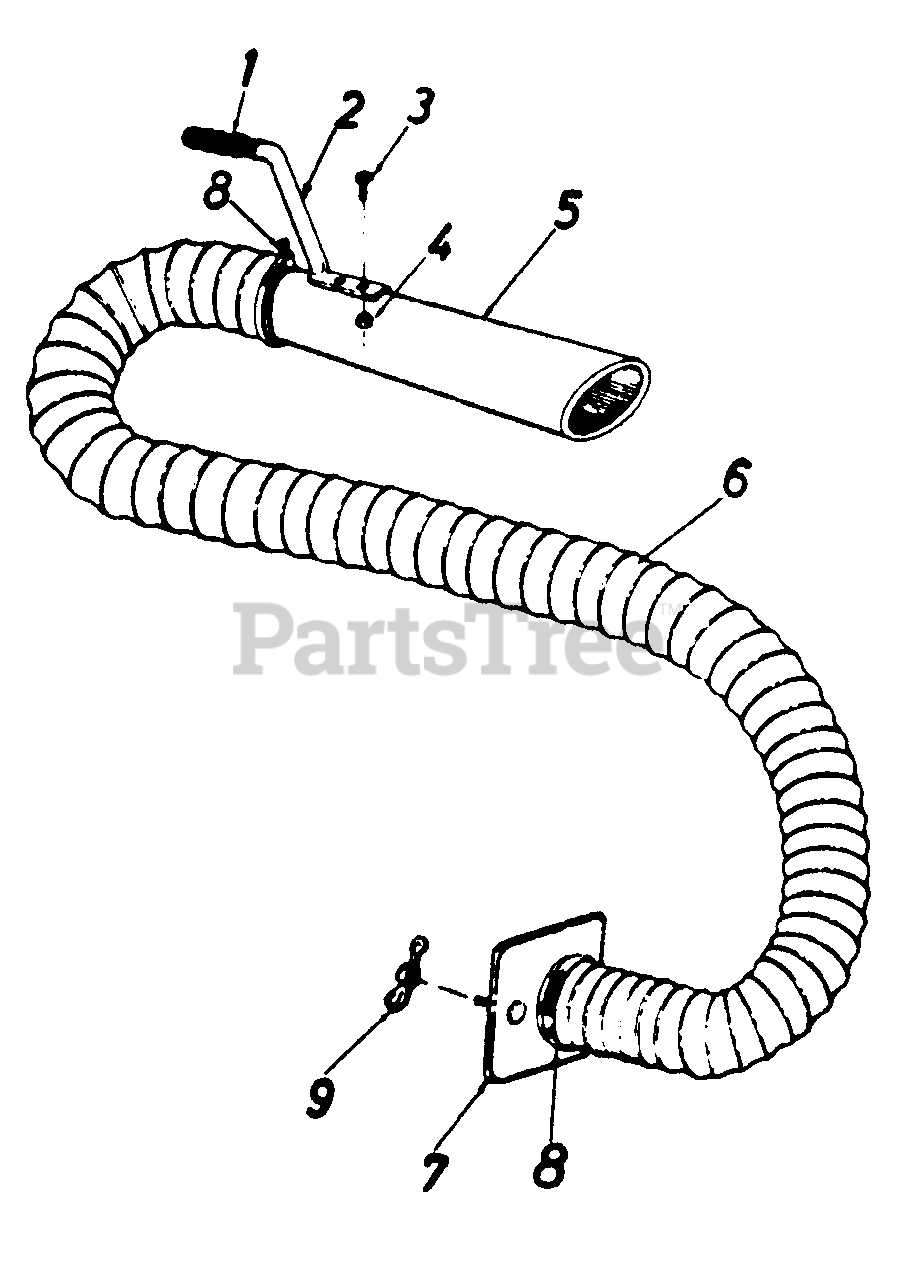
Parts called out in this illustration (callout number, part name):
1	Handle Grip
2	Handle
3	Truss Sems Scr. 10-24 x 1/2" Lg.
4	Hex Nut 10-24 Thd.
5	Hose Nozzle
6	FlexibleHose4" Dia. x 10' Lg.
7	Hose Adapter Plate
8	Hose Clamp - For 4" Dia. Hose
9	Wing Nut 1/4-20 Thd.
